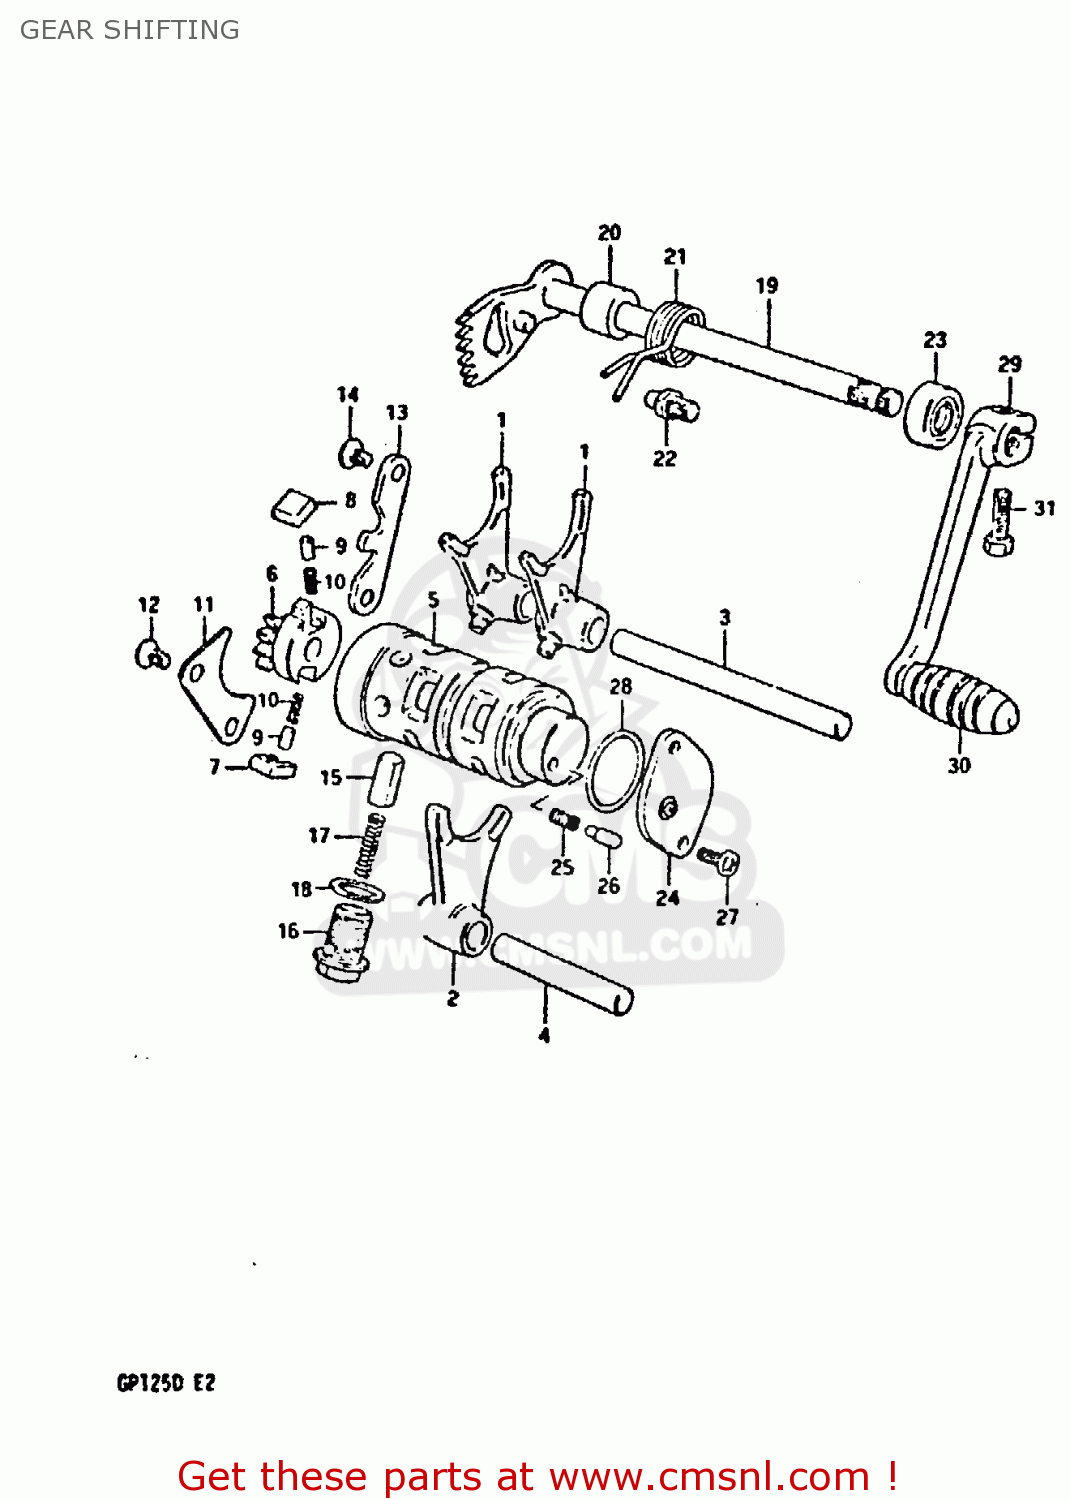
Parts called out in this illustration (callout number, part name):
1	FORK,GEAR SHIFT NO.1
2	FORK,GEAR SHIFT NO.2
3	SHAFT,GEAR SHIFT FORK
4	SHAFT,GEAR SHIFT FORK
5	CAM,GEAR SHIFT
6	RETAINER,GEAR SHIFT CAM
7	PAWL,GEAR SHIFT NO.1
8	PAWL,GEAR SHIFT NO.2
9	PIN(5X8)
10	SPRING
11	LIFTER,GEAR SHIFT PAWL
12	SCREW
13	GUIDE,GEAR SHIFT CAM
14	SCREW
15	STOPPER,GEAR SHIFTING
16	HOUSING,GEAR SHIFT CAM STOPPER
17	SPRING
18	GASKET(14X19.2X2) (NAS)
19	SHAFT,GEAR SHIFT
20	SPACER(12X20X15.3)
21	SPRING
22	STOPPER,GEAR SHIFT CAM
23	OIL SEAL
24	BODY,GEAR SHIFT SWITCH
25	SPRING
26	PIN(5X15.5)
27	SCREW
28	O-RING (D:2.4 ID:26.2)
29	LEVER ASSY,GEAR SHIFT
30	RUBBER,GEAR SHIFT PEDAL
31	BOLT
